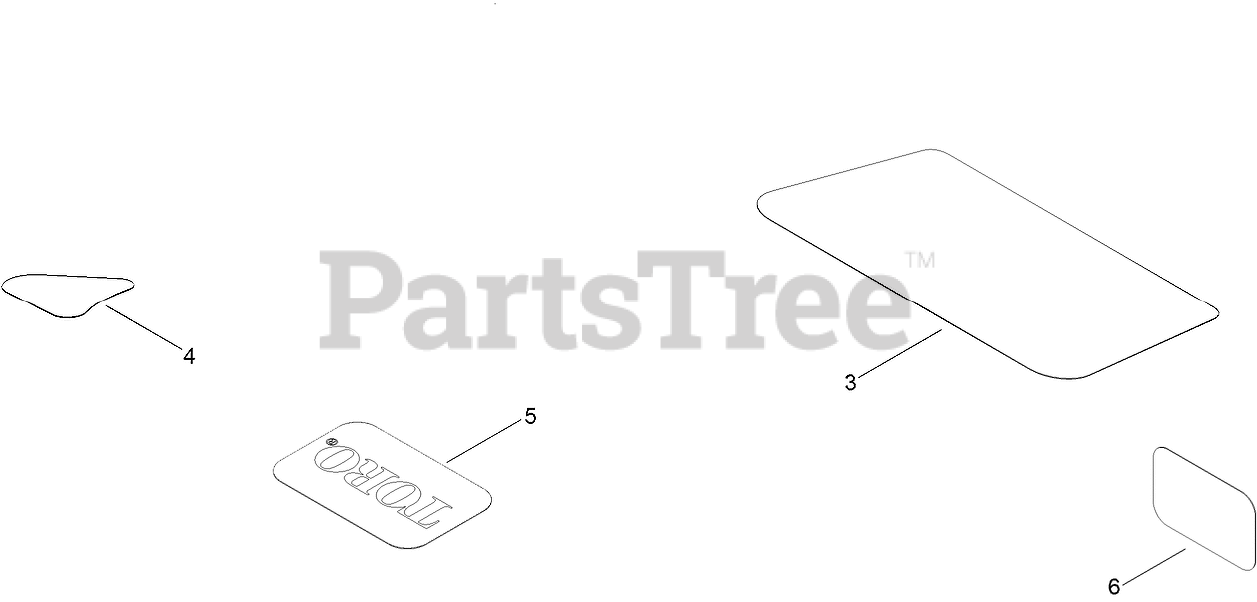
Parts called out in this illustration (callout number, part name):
3	DECAL-ENGINE
4	DECAL-DRAIN, OIL
6	PLACARD-INTAKE
